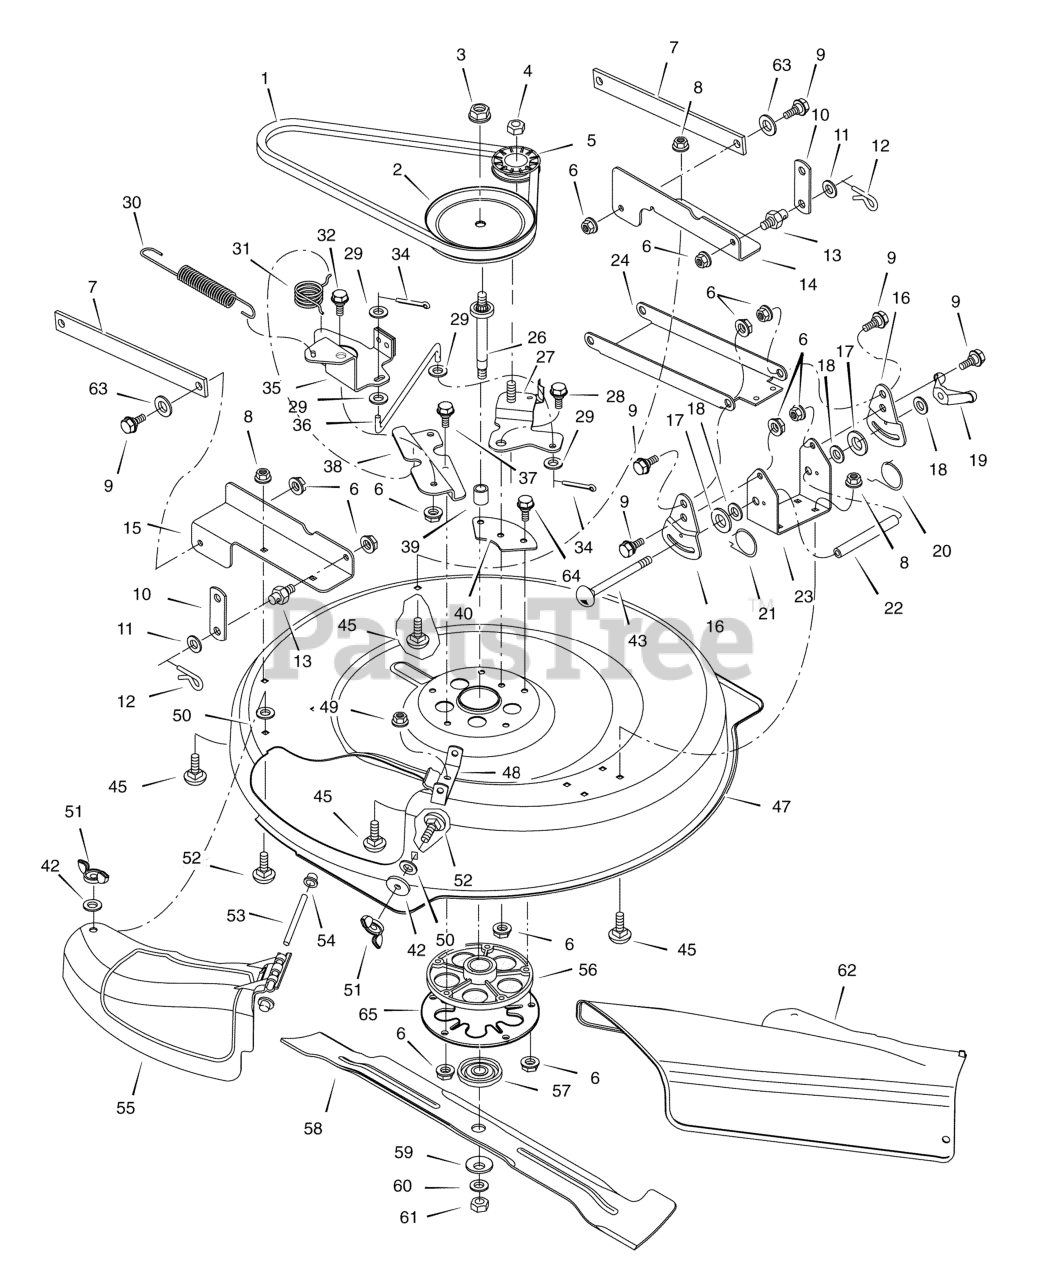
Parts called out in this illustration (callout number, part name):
1	BELT, Blade Drive
2	PULLEY, Input
3	LOCKNUT
4	NUT, Flange
5	PULLEY, Idler
6	NUT, Flange
8	NUT, Flange
9	BOLT, Shoulder
12	PIN, Hair
13	PIN, Threaded Shoulder
14	BRACKET, Left Rear
15	BRACKET, Right Rear
16	PLATE, Adjustment
17	PAD, Friction
19	WINGNUT
20	SPRING, Left Torsion
21	SPRING, Right Torsion
22	TUBE, Spacer
23	BRACKET, Deck
24	HANGER, Front
26	SHAFT, Splined
27	ARM ASSEMBLY , Idler
28	BOLT, Shoulder
29	WASHER
30	SPRING, Extension
31	SPRING, Torsion
32	BOLT, Shoulder
34	PIN, Cotter
35	ARM ASSEMBLY, Brake
36	LINK, Idler Arm
38	BRACKET, Brake Mounting
39	SPACER, Jackshaft
40	PLATE, Idler Mounting
43	BOLT, Carriage
45	BOLT, Carriage
47	HOUSING, Blade
48	HINGE, Mulching Cover
49	NUT, Flange
50	NUT, Speed
51	WINGNUT
52	BOLT, Carriage
53	ROD, Chute Deflector
54	CAP, Push
55	COVER, Mulch
56	MANDREL HOUSING
57	ADAPTER, Blade
59	WASHER, Cup
61	NUT, Blade Mount
62	DEFLECTOR, Chute
65	PLATE, Jackshaft Support
